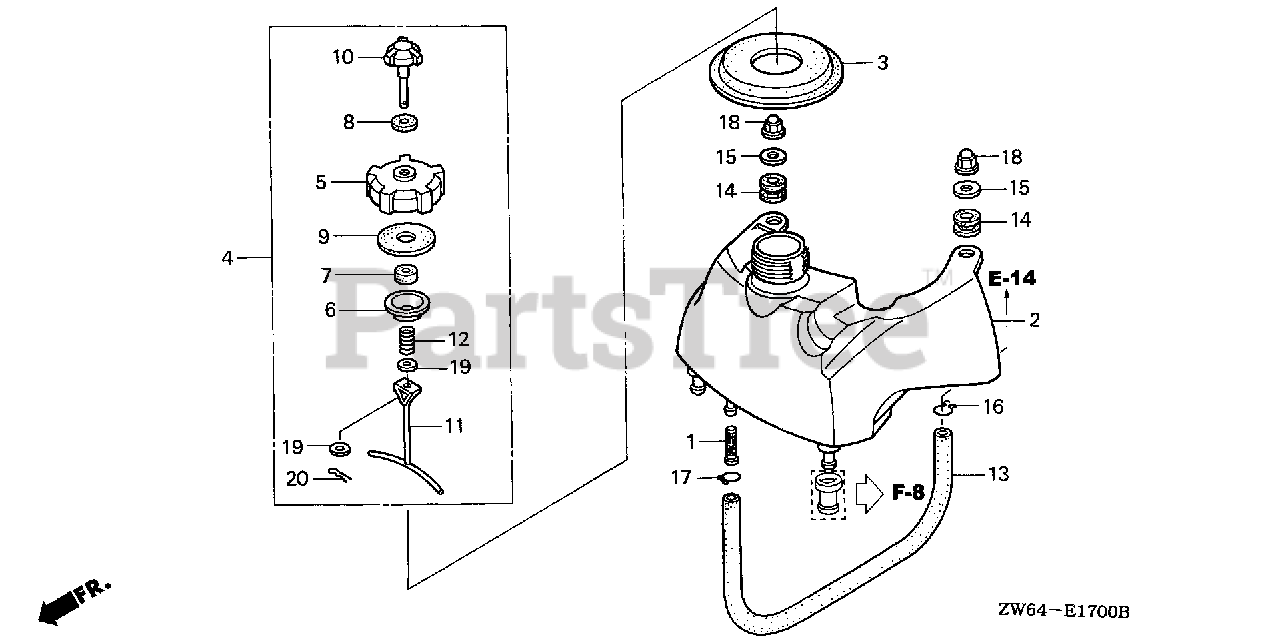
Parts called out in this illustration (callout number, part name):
1	FILTER, FUEL
2	TANK, FUEL
3	RUBBER A, TANK MOUNTING
4	CAP ASSY., FUEL TANK
5	BODY, FUEL CAP
6	INNER, FUEL CAP
7	SPONGE, FUEL CAP BREATHER
8	GASKET, VALVE
9	GASKET, FUEL CAP
10	VALVE, BREATHER
11	LINK, FUEL CAP
12	SPRING, FUEL CAP
13	TUBE, FUEL
14	CUSHION, AIR CLEANER
15	WASHER (6.5X18)
16	CLIP, TUBE (B10) (NOT AVAILABLE)
17	CLIP, TUBE (B12)
18	NUT, CAP (6MM)
19	WASHER, PLAIN (4MM)
20	PIN, LOCK (4MM)
